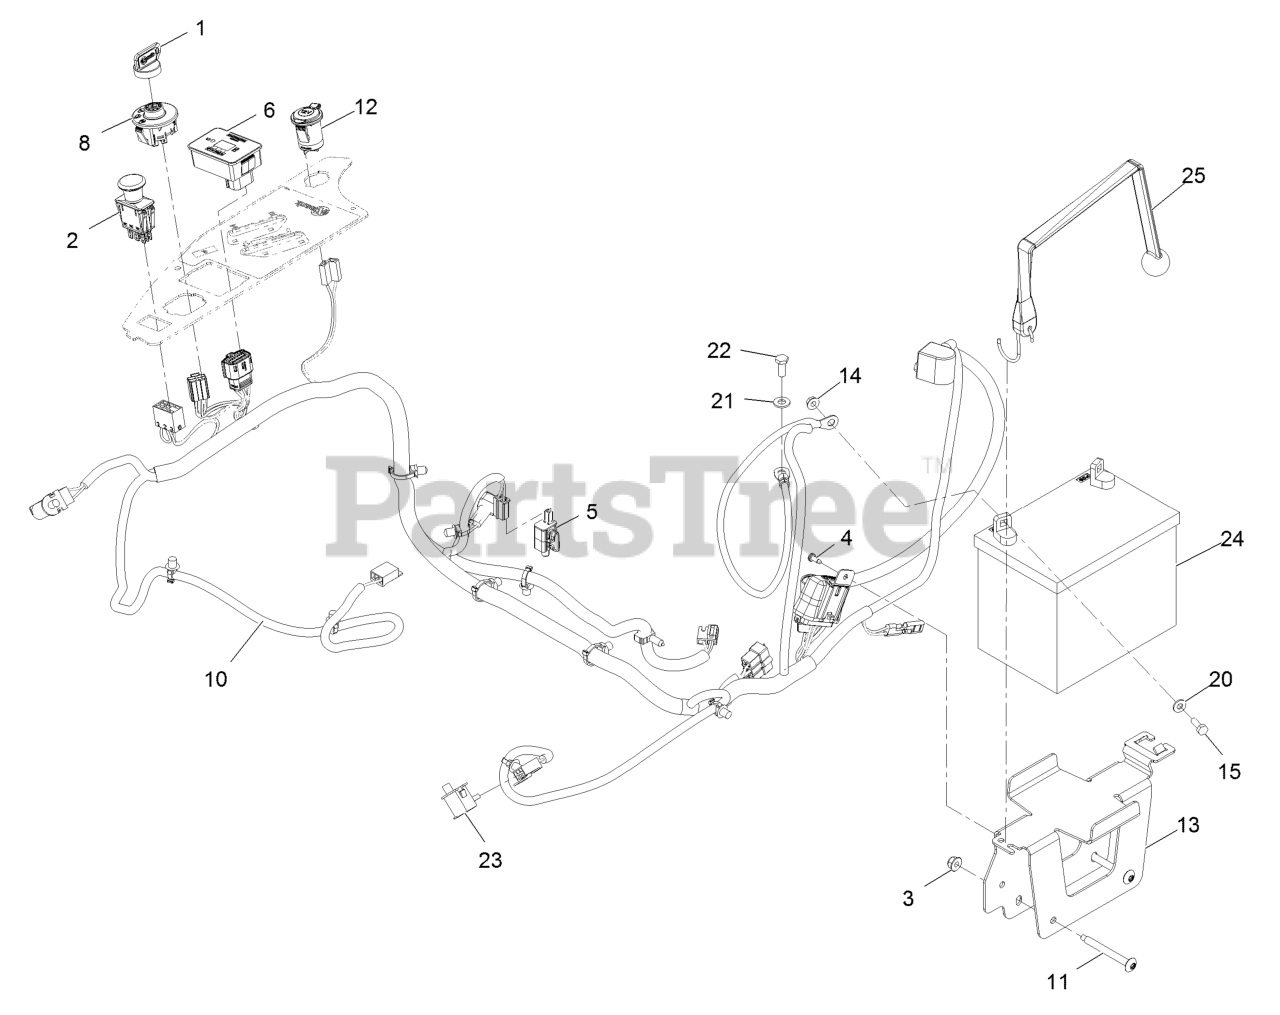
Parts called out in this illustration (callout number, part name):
1	KEYS-IGNITION (SPARE PAIR
1	KEY-IGNITION
2	SWITCH-PTO
3	NUT-HF, NI
4	SCREW-FORMING, THREAD
6	MODULE ASM
10	HARNESS-WIRE
11	SCREW-TORX
12	PORT-POWER, 12V
13	TRAY-BATTERY
15	SCREW-HH
20	WASHER-FLAT
21	WASHER-PLAIN
22	SCREW-HH
23	SWITCH-BAIL
24	Battery
25	STRAP-BUNGEE
